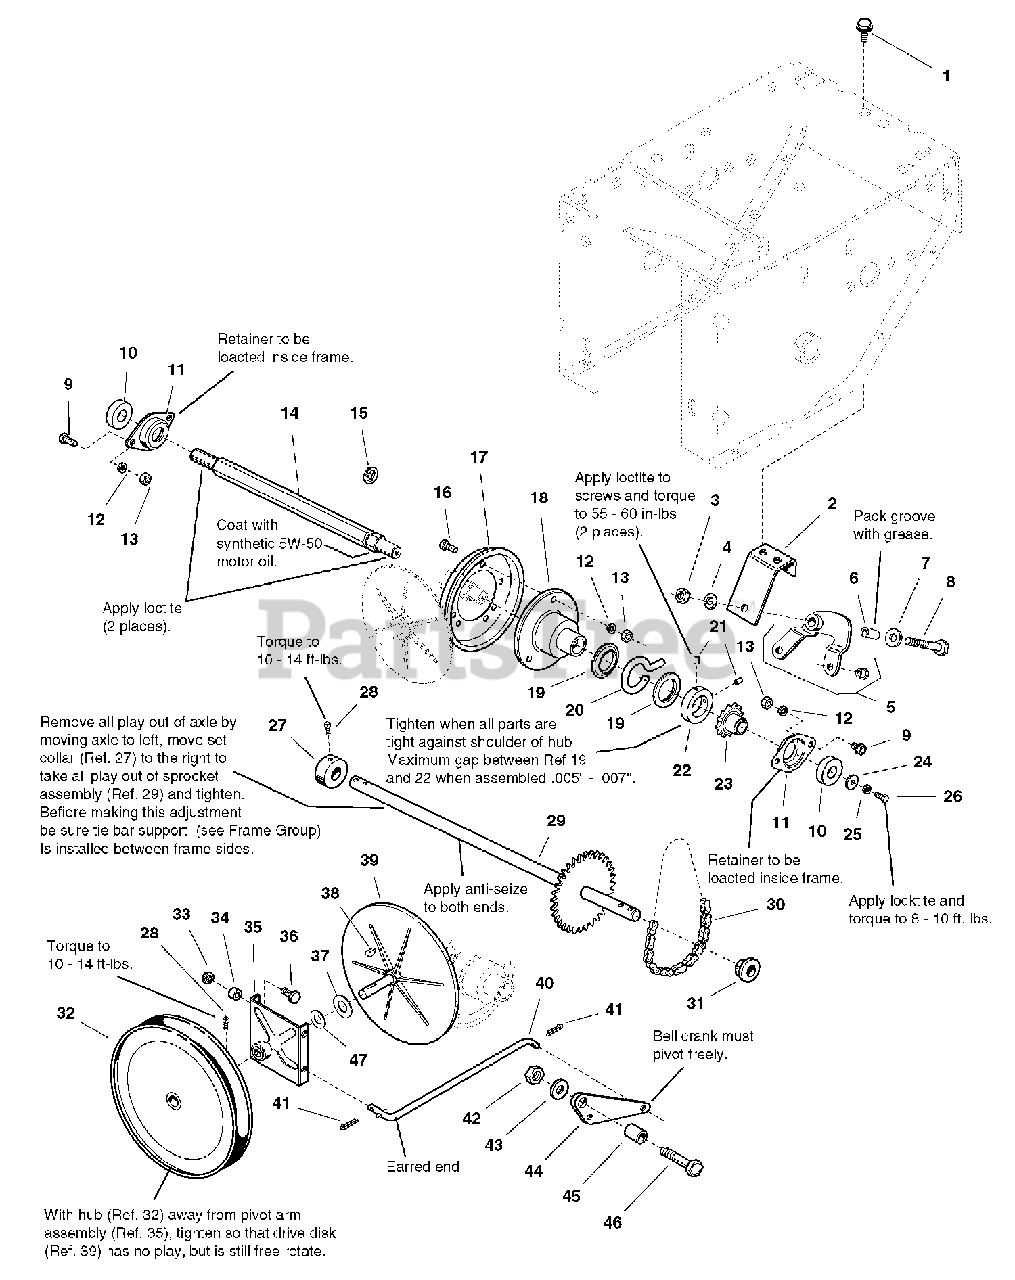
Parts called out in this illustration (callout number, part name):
1	CAPSCREW, Taptite, 5/16-18 x 5/8
2	BRACKET
3	NUT, Hex, 3/8-16
4	LOCKWASHER, 3/8
5	SHIFT ARM ASSEMBLY, w/Bushing
6	BUSHING
7	WASHER
8	CAPSCREW, Hex Head, 3/8-16 x 2
9	CAPSCREW, Hex Head, 5/16-18 x 5/8
10	BEARING, Ball
11	RETAINER, Bearing
12	LOCKWASHER, 5/16
13	NUT, Hex, 5/16-18
15	E-RING, Retaining
16	CAPSCREW, Hex Head, 5/16-18 x 3/4
17	DISC, Friction
18	HUB, Friction Disc
19	COLLAR, Thrust
21	SET SCREW, Hex Socket, Cup Point, 1/4-20 x 3/8
22	COLLAR, Set
23	SPROCKET, 10T
24	WASHER
25	LOCKWASHER, 1/4
26	CAPSCREW, Hex Head, 1/4-20 x 3/4
27	COLLAR, Set
28	SET SCREW, Square Head, Cup Point, 5/16-18 x 1/2
29	AXLE & SPROCKET ASSEMBLY
30	CHAIN, Roller, #40 x 25
32	PULLEY, Traction
33	NUT, Centerlock, Hex Flange Head, 5/16-18
35	PIVOT ASSEMBLY
36	CAPSCREW, Hex Head, 5/16-18 x 5/8
37	WASHER
38	KEY, Hi-Pro
39	DRIVE, Disc, w/Spindle
41	PIN, Cotter 1/8 x 3/4
42	NUT, Hex Lock, ESNA, 5/16-18
43	WASHER, Flat
45	BUSHING
46	CAPSCREW, Hex Head, 5/16-18 x 1-3/4
47	WASHER, 5/8
